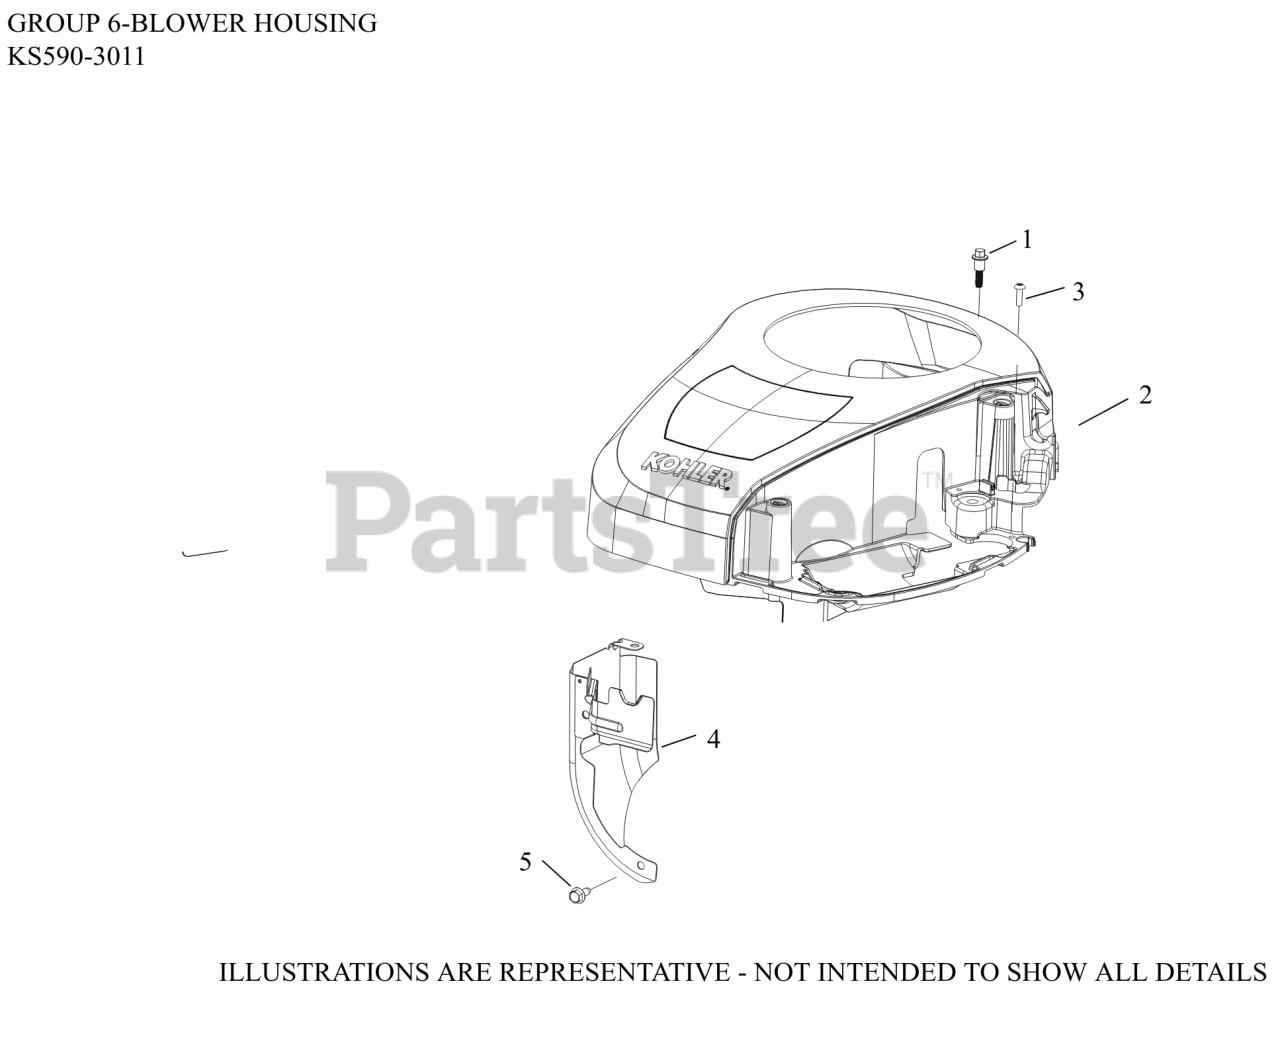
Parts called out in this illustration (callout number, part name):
1	SCREW, SHD THD FRM M6X1X26
2	KIT, BLOWER HOUSING
3	SCREW, HI-LOW
4	BAFFLE, BARREL ASSY
5	SCREW, THREAD FORMING
